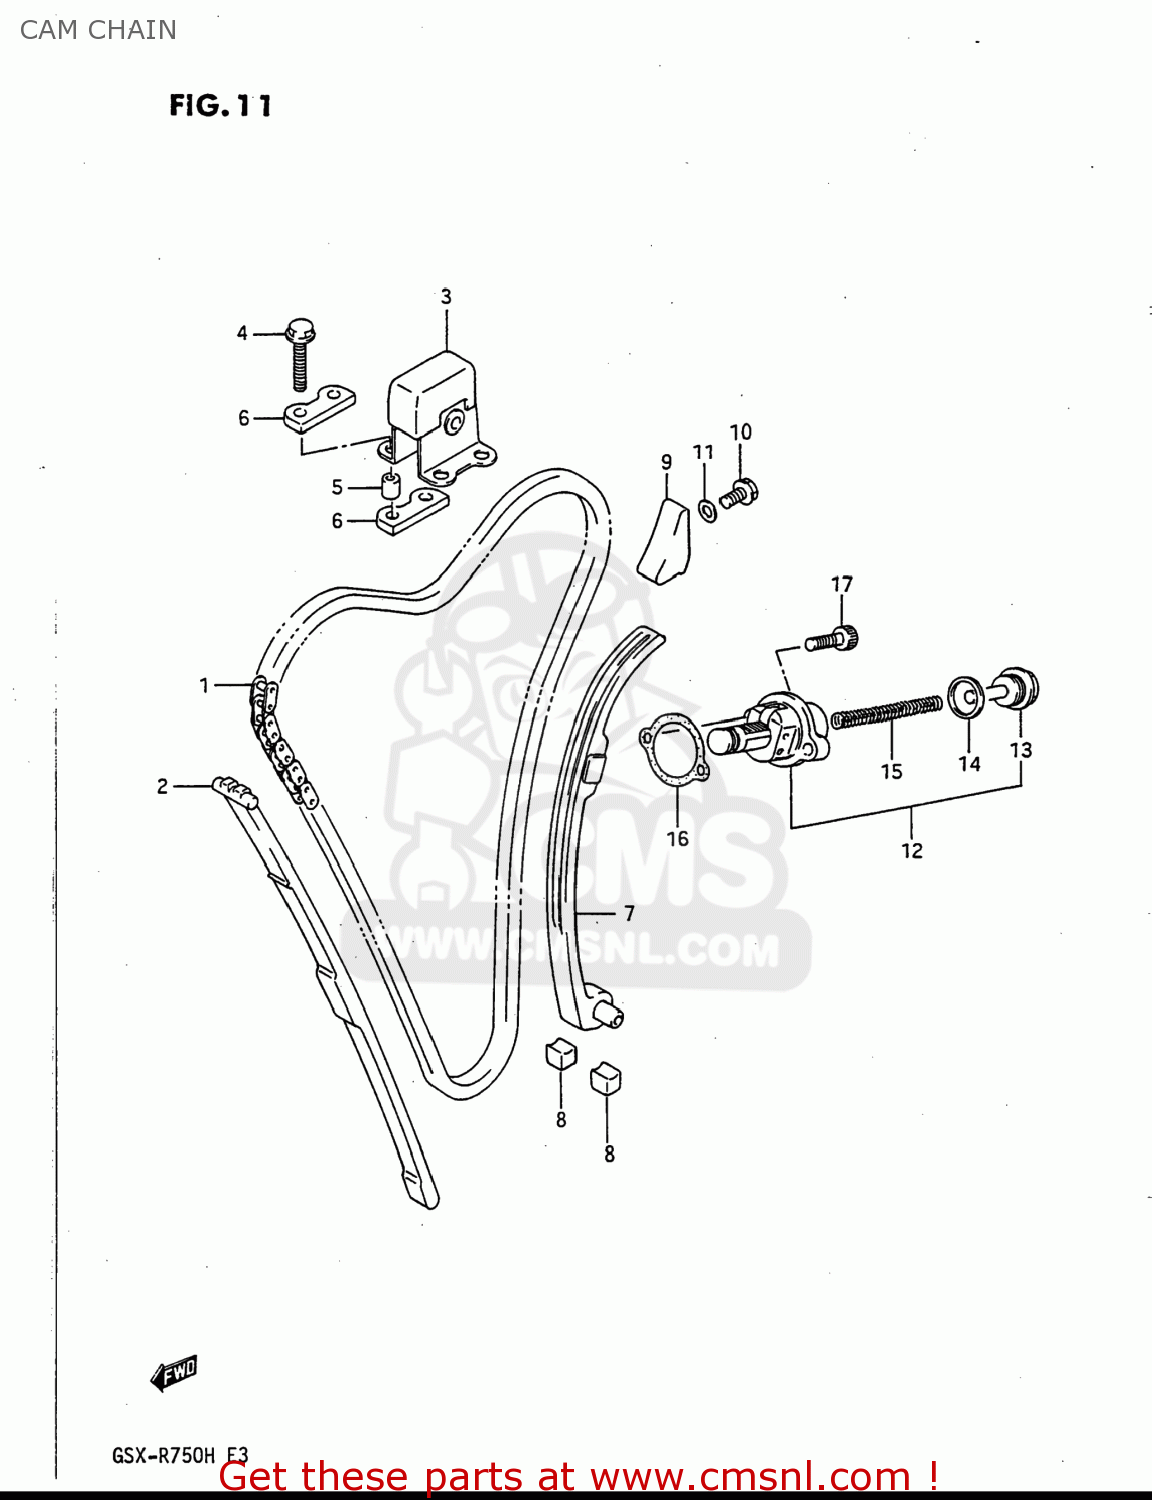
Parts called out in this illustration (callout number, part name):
1	CHAIN,CAMSHAFT DRIVE
2	GUIDE,CAM CHAIN NO.1
3	IDLER,CAM CHAIN
4	BOLT
5	SPACER
6	GUIDE,CAM CHAIN
7	TENSIONER,CAM CHAIN
8	CUSHION,CAM CHAIN TENSIONER
9	GUIDE,CAM CHAIN NO.2
10	BOLT
11	GASKET(5.8X13X1.2) (NAS)
12	ADJUSTER ASSEMBLY,TENSIONER
13	PLUG
14	GASKET (NAS)
15	SPRING
16	GASKET,TENSIONER ADJUSTER (NAS)
17	BOLT
